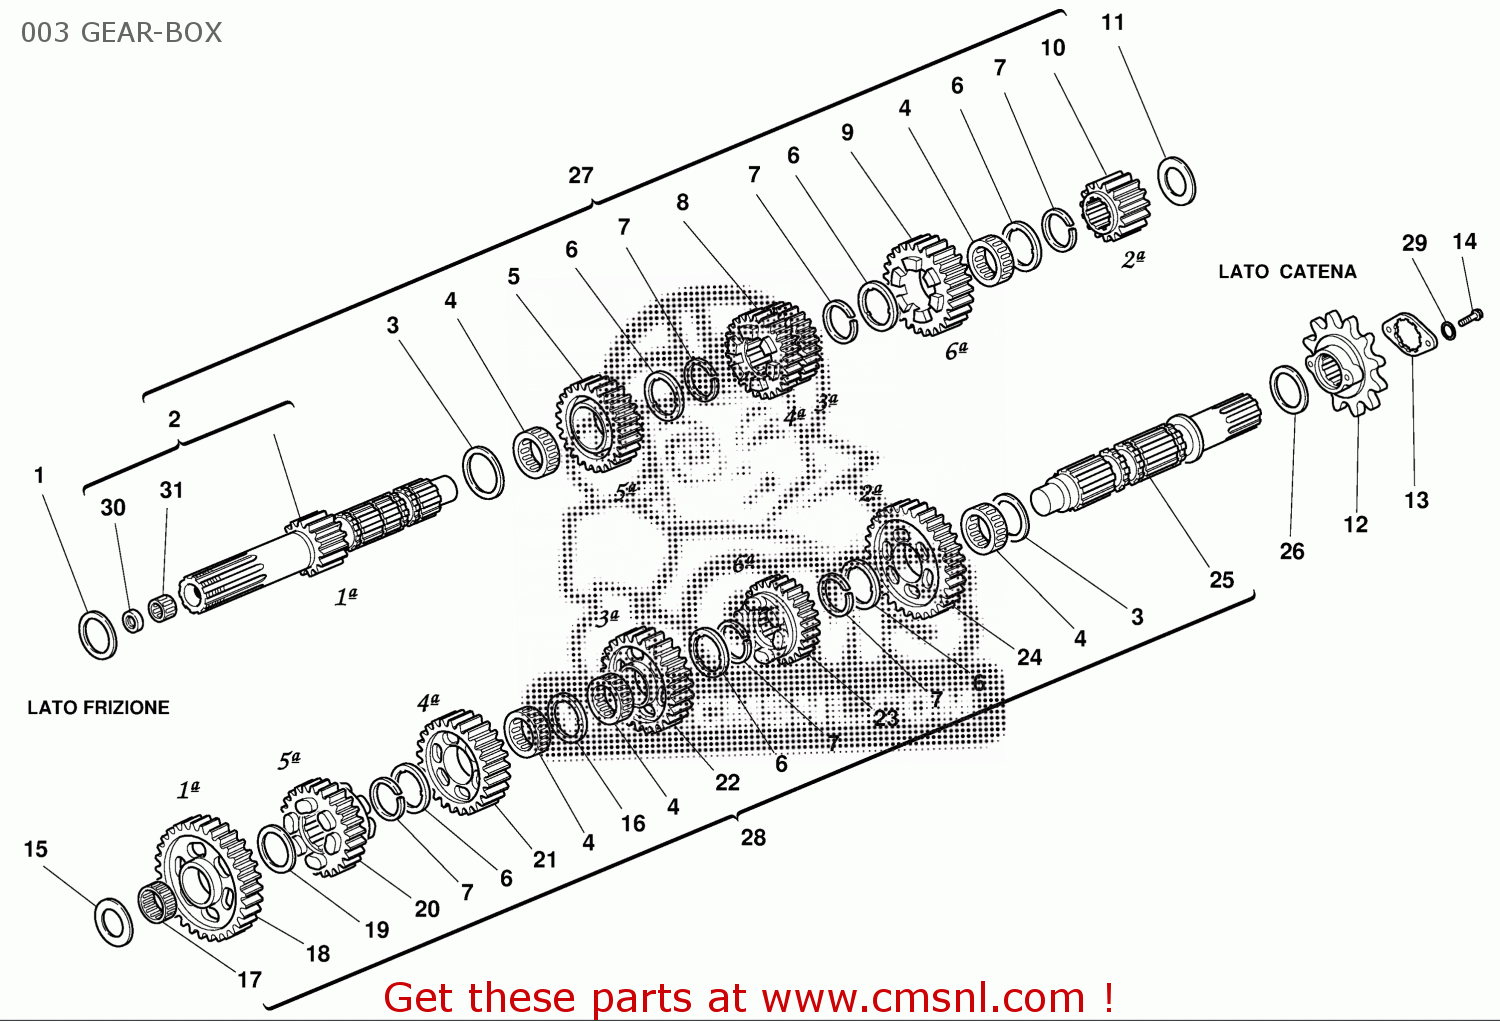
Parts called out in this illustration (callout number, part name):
1	THRUST WASHER 25.2X32.5X1
2	MAIN SHAFT T15
3	THRUST WASHER 0.5 MM
4	BEARING, NEEDLE
5	GEAR DRIVE 5TH SPEED T23
6	THRUST WASHER 0.5 MM
7	SPRING RING
8	GEAR DRIVE 3/4TH SPEED T20/22
9	GEAR DRIVE 6TH SPEEDTT24
10	GEAR, 2ND DRIVE, NT:17
11	THRUST WASHER 20.3X32X2
12	CHAIN PINION T15
13	PLATE, DRIVE SPROCKET FIXING
14	SCREW
15	THRUST WASHER 20.3X32X2
16	THRUST WASHER 0.5 MM
17	BEARING, NEEDLE
18	DRIVEN GEAR 1ST SPEED T37
19	THRUST WASHER 1 MM
20	DRIVEN GEAR 5TH SPEED T24
21	DRIVEN GEAR 4TH SPEED T:26
22	DRIVEN GEAR 3RD SPEED T28
23	DRIVEN GEAR 6TH SPEED T23
24	DRIVEN GEAR 2ND SPEED T30
25	DRIVEN SHAFT
26	THRUST WASHER 0.8 MM
27	COMPLETE MAIN SHAFT
28	COMPLETE LAY SHAFT
29	WASHER, SPRING
30	OIL SEAL
31	NEEDLE BUSH HK0810
